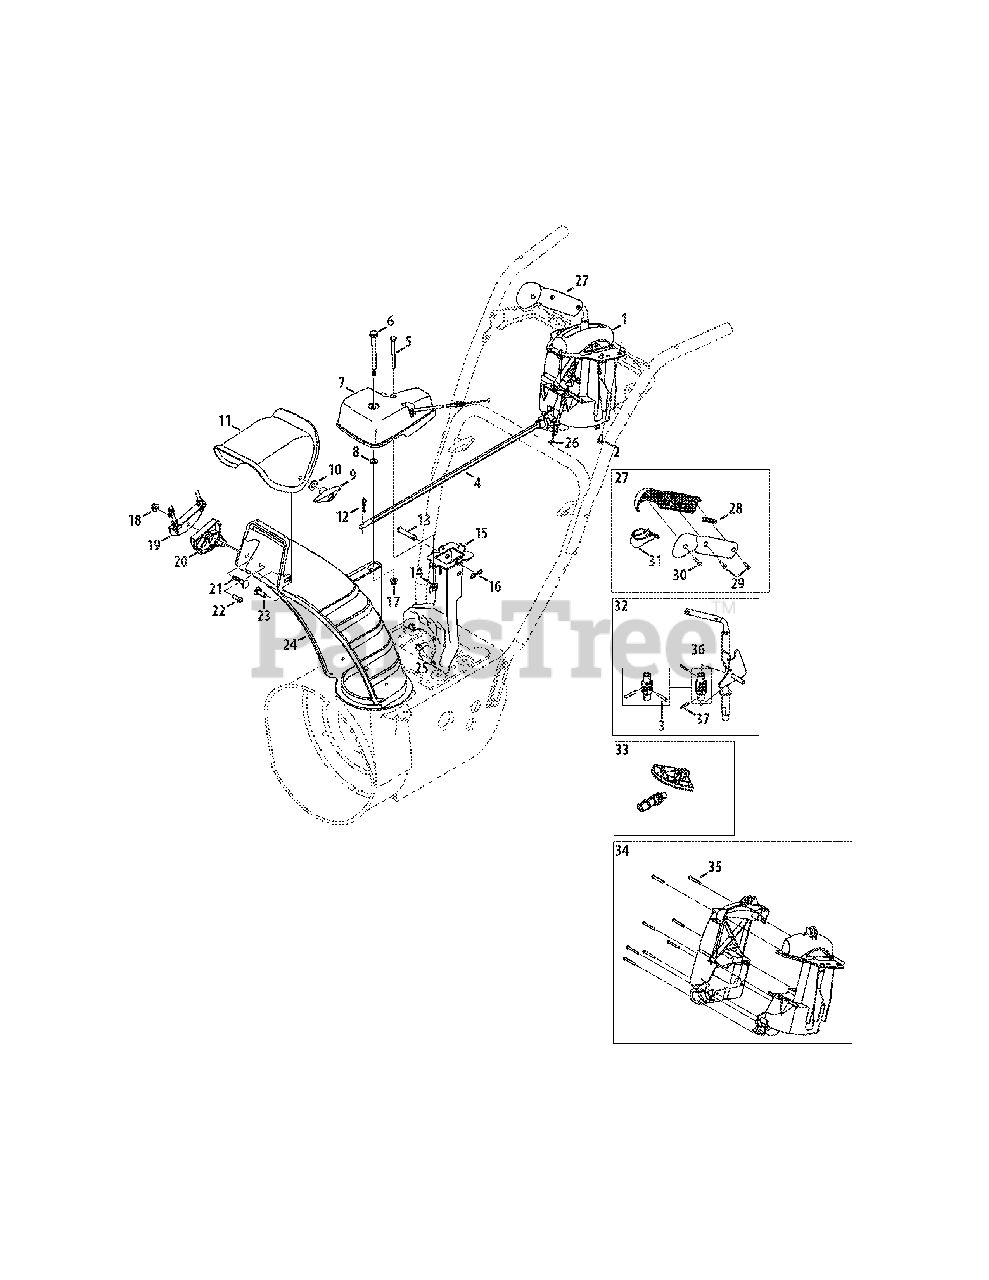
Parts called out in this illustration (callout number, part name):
1	4-Way Chute Control™ Assembly
2	Hi-Lo Screw, 1/4-15 x 0.5
3	Roll Pin
4	Chute Rod
5	Hex Screw, 1/4-20 x 3.00
6	Flange Shoulder Screw
7	4-Way Chute Gearbox Assembly
8	Flat Washer, .25 x .630 x .0515
9	Wing Knob
10	Flat Washer, .349 x .879 x .063
11	Upper Chute
12	Cotter Pin
13	Clevis Pin
14	Wing Nut, 1/4-20
15	Chute Support Bracket
16	Bow Tie Cotter Pin
17	Flange Lock Nut, 1/4-20
18	Flange Lock Nut, 5/16-18
19	Cable Bracket
20	Chute Tilt Cable Guide
21	Carriage Bolt, 5/16-18 x 1.50
22	Hi-Lo Screw, 1/4-15 x .75
23	Carriage Bolt, 5/16-18 x 1.0
24	Lower Chute
25	Hex Screw, 5/16-24 x .750
26	4-Way Cable
27	Handle Assembly
28	Handle Plunger
29	Screw, Mach., #8-32 x .750
30	Screw, #8 x 1.00
31	Handle Lever
32	Shift Assembly
33	Gear Set Assembly
34	Handle Housing Assembly
35	Screw, #8-18 x 1.250
36	Joint Block Assembly
